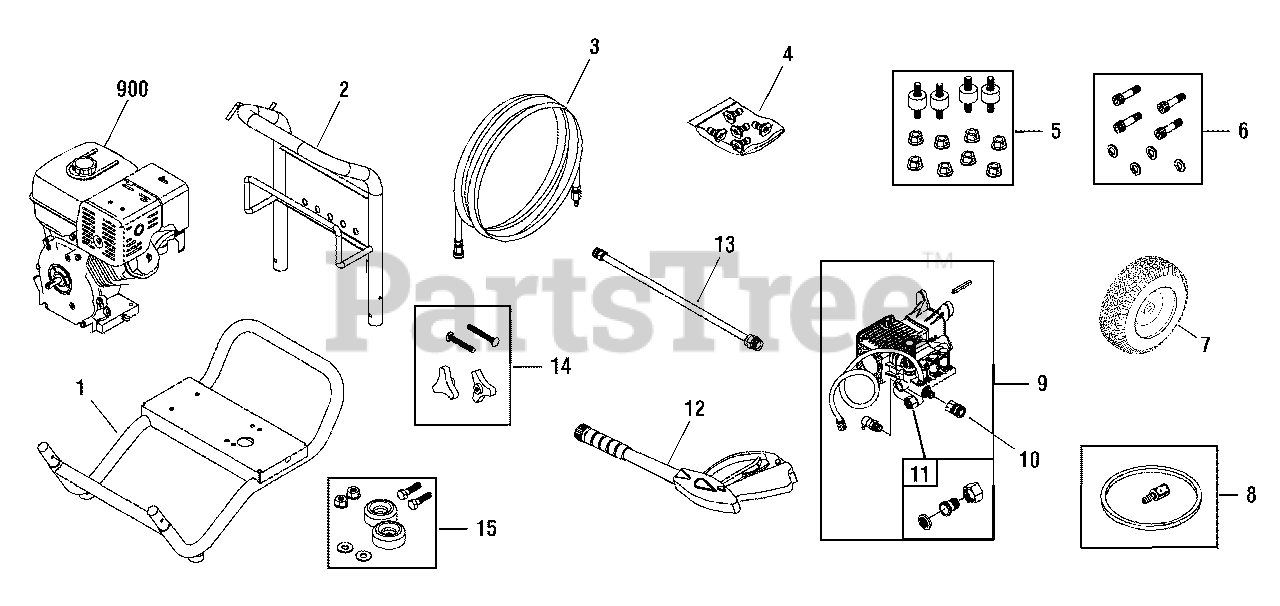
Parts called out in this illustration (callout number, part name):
4	KIT, QC Nozzles
5	KIT, Hardware, Engine Mounting
6	KIT, Hardware, Pump Mounting
9	PUMP
10	FITTING
11	ADAPTER, Garden Hose
12	GUN
13	EXTENSION, QC
14	KIT, Hardware, Handle
15	MOUNT, Vibration
900	* ENGINE
